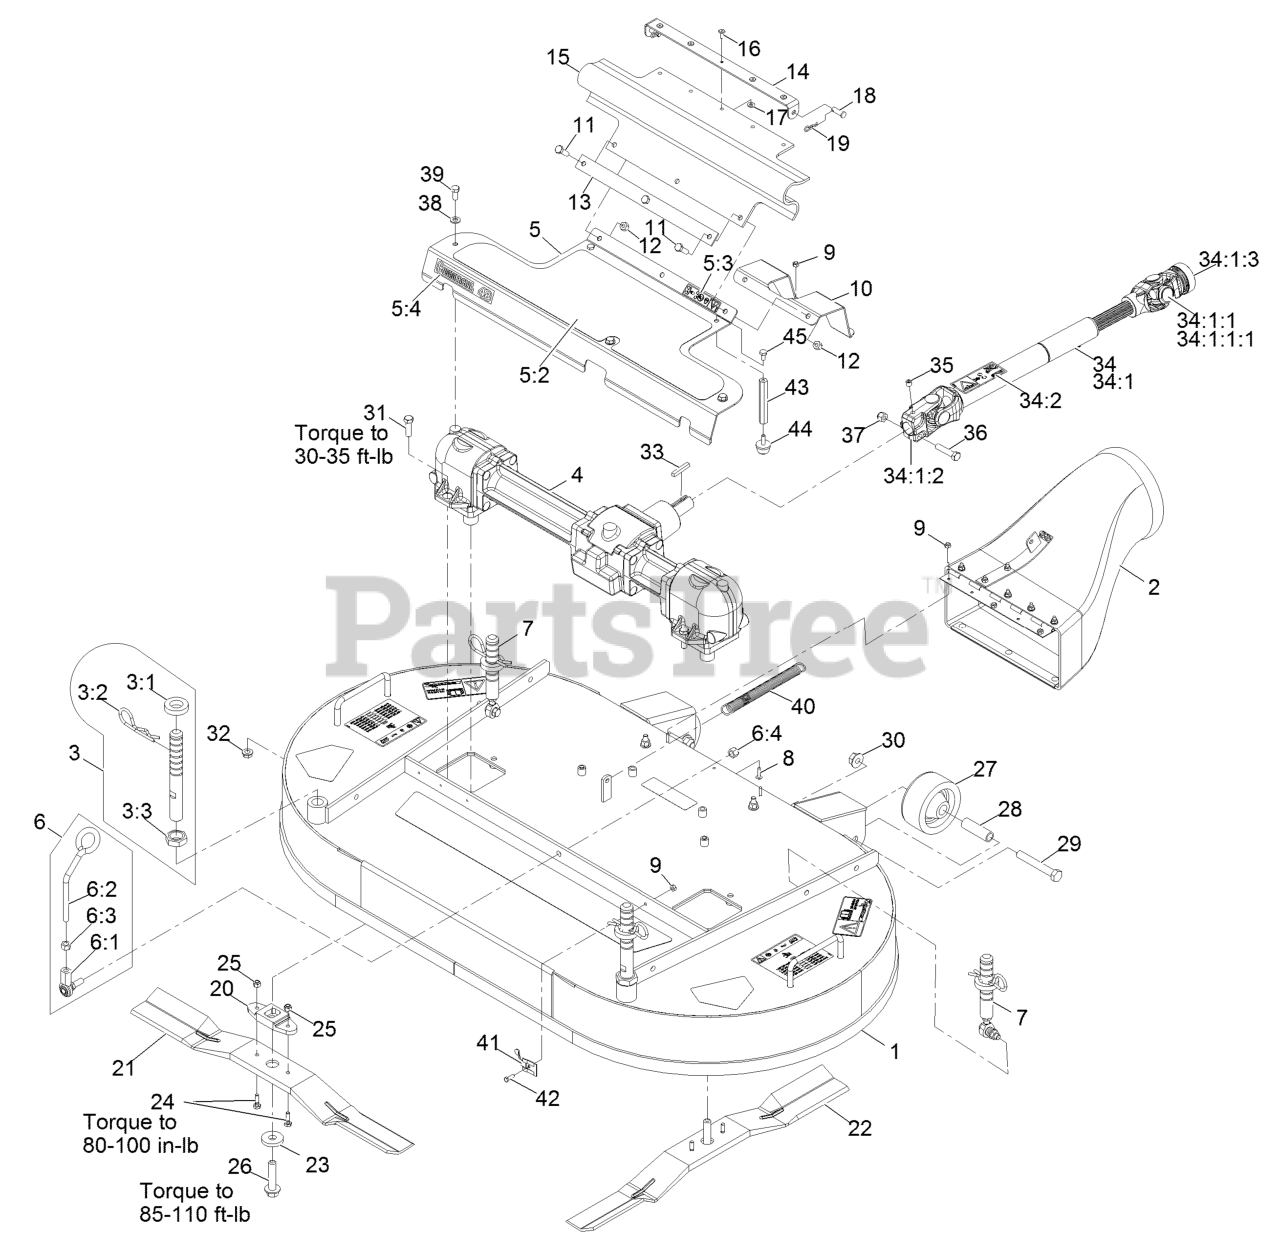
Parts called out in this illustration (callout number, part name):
1	DECK DECAL AND BAFFLE ASM
2	DISCHARGE TUBE ASM
3	FRONT DECK HEIGHT ADJUST
3:1	SPACER-DECK SUPPORT
3:2	PIN-CUT HEIGHT
3:3	NUT-JAM
4	GEAR BOX ASM
5	ASM,GEARBOX COVER 48 W/DE
5:2	PAD-ANTI SKID
5:3	DECAL-DANGER
5:4	DECAL,COMMERCIAL 48
6	DECK LATCH ASM
6:1	BALLJOINT-RH
6:2	LATCH-DECK
6:3	NUT-HEX
6:4	NUT-LOCK
7	REAR DECK HEIGHT ADJUST A
8	SCREW-HEAD, TRUSS
9	NUT-LOCK, NI
10	GUARD-DRIVE SHAFT
11	SCREW-HH
12	NUT-LOCK, NI
13	STRAP-DRIVE, LINE COVER
14	BRACKET-GUARD, PTO
15	GUARD-PTO
16	RIVET-BLIND
17	WASHER-FLAT
18	PIN-CLEVIS
19	PIN-COTTER
20	DRIVER-BLADE
21	BLADE,25 INCH RH
22	BLADE,25 INCH LH
24	BOLT-SHEAR
25	NUT-LOCK, NI
26	BOLT-BLADE
27	ROLLER-DECK
28	SPACER-ROLLER
29	SCREW-HH
30	NUT-HHF
31	SCREW-HH
32	NUT-HHF, WHIZ
33	KEY-SQUARE
34	DRIVE SHAFT ASM
34:1	Drive Shaft-Telescoping
34:1:1	U-JOINT KIT
34:1:1:1	FITTING-GREASE
34:1:2	YOKE-KEYED
34:1:3	YOKE-QUICK DISCONNECT
34:2	DECAL-DANGER, DRIVELINE
35	SCREW-SET, HSH
36	SCREW-HH
37	NUT-LOCK, NI
38	WASHER-PLAIN
39	SCREW-HH
40	SPRING-EXTENSION
41	CLIP-DECK, HOLD UP ROD
43	STAND-OFF
45	SCREW-HH
